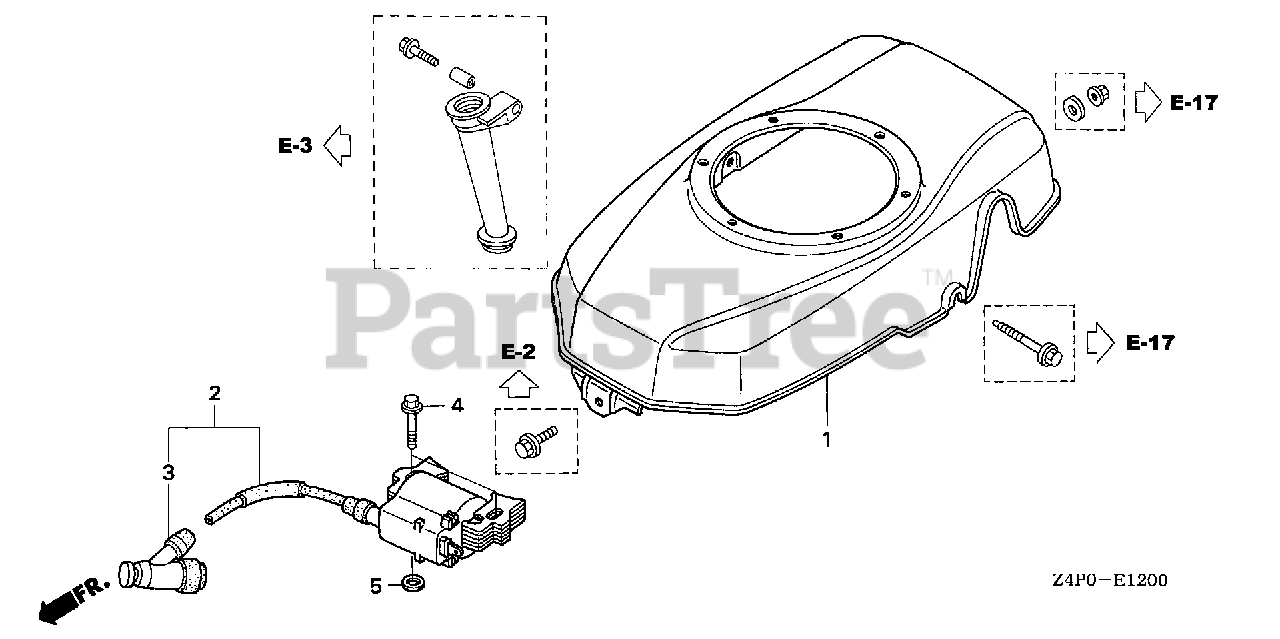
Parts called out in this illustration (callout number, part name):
1	COVER, FAN *R280* (POWER RED)
1	COVER, FAN *NH1* (BLACK)
2	COIL ASSY., IGNITION & CAP ASSY. NOISE SUPPRESSOR (TOYO)
4	BOLT, FLANGE (6X28) (CT200) Use up to Engine SN 1530314.
5	WASHER, PLAIN (6MM)
